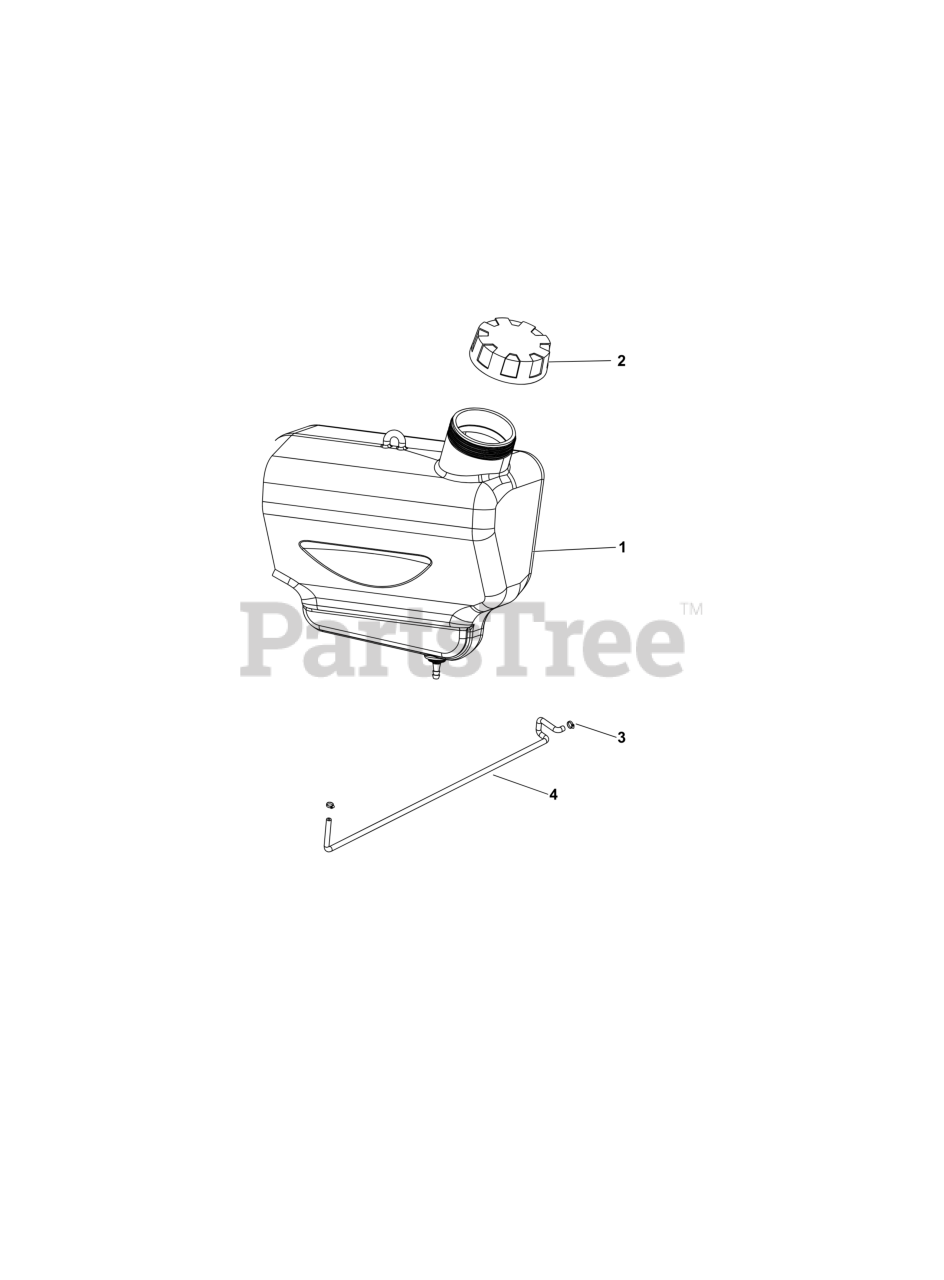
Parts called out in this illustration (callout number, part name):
1	TANK, Fuel
2	CAP, Fuel Tank
4	HOSE, Fuel
